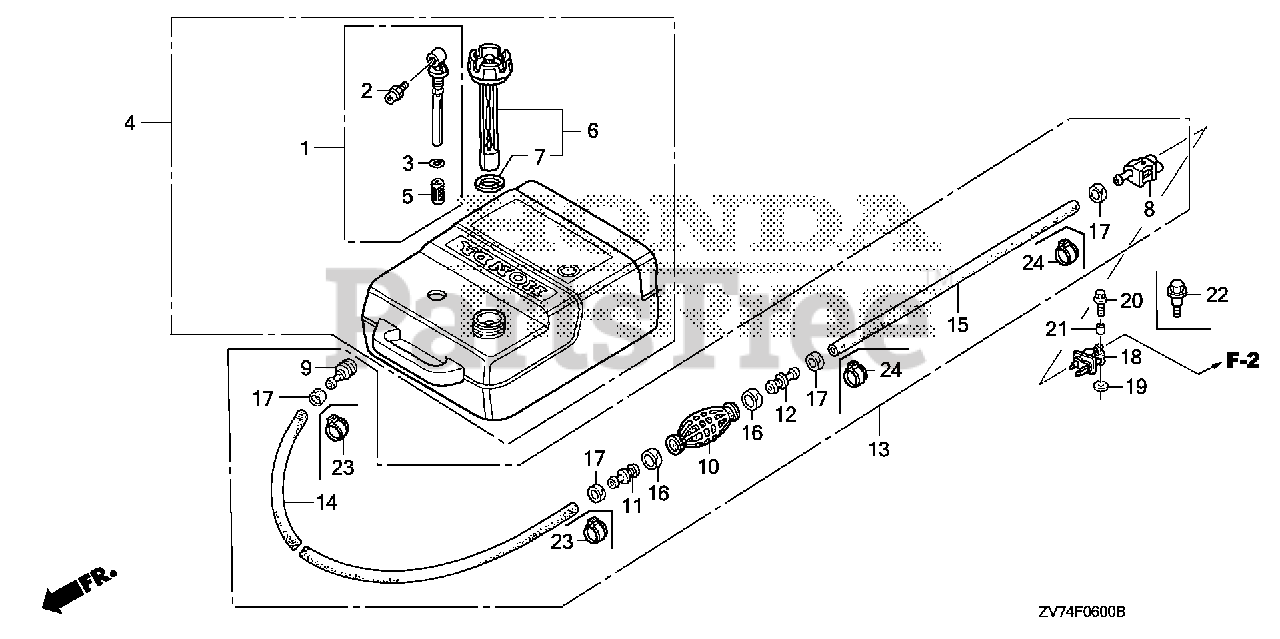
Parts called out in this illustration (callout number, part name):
1	JOINT ASSY., FUEL
2	FITTING, QUICK DISCONNECT
4	TANK ASSY., FUEL
5	FILTER, FUEL
6	CAP, FUEL FILLER
7	GASKET, FUEL CAP
8	CONNECTOR ASSY., FUEL (A)
9	CONNECTOR, FUEL
10	BULB, PRIMER
11	VALVE, IN.
12	VALVE, OUTLET
13	TUBE ASSY., FUEL
14	TUBE, FUEL LONG (7.3X2000)
15	TUBE, FUEL SHORT (6.3X500)
16	BAND, TUBE CLIP (20MM)
17	BAND, TUBE CLIP (12.5MM)
18	CONNECTOR ASSY., FUEL (B)
19	WASHER, PIVOT
22	BOLT, SPECIAL (6X22) (CT200)
